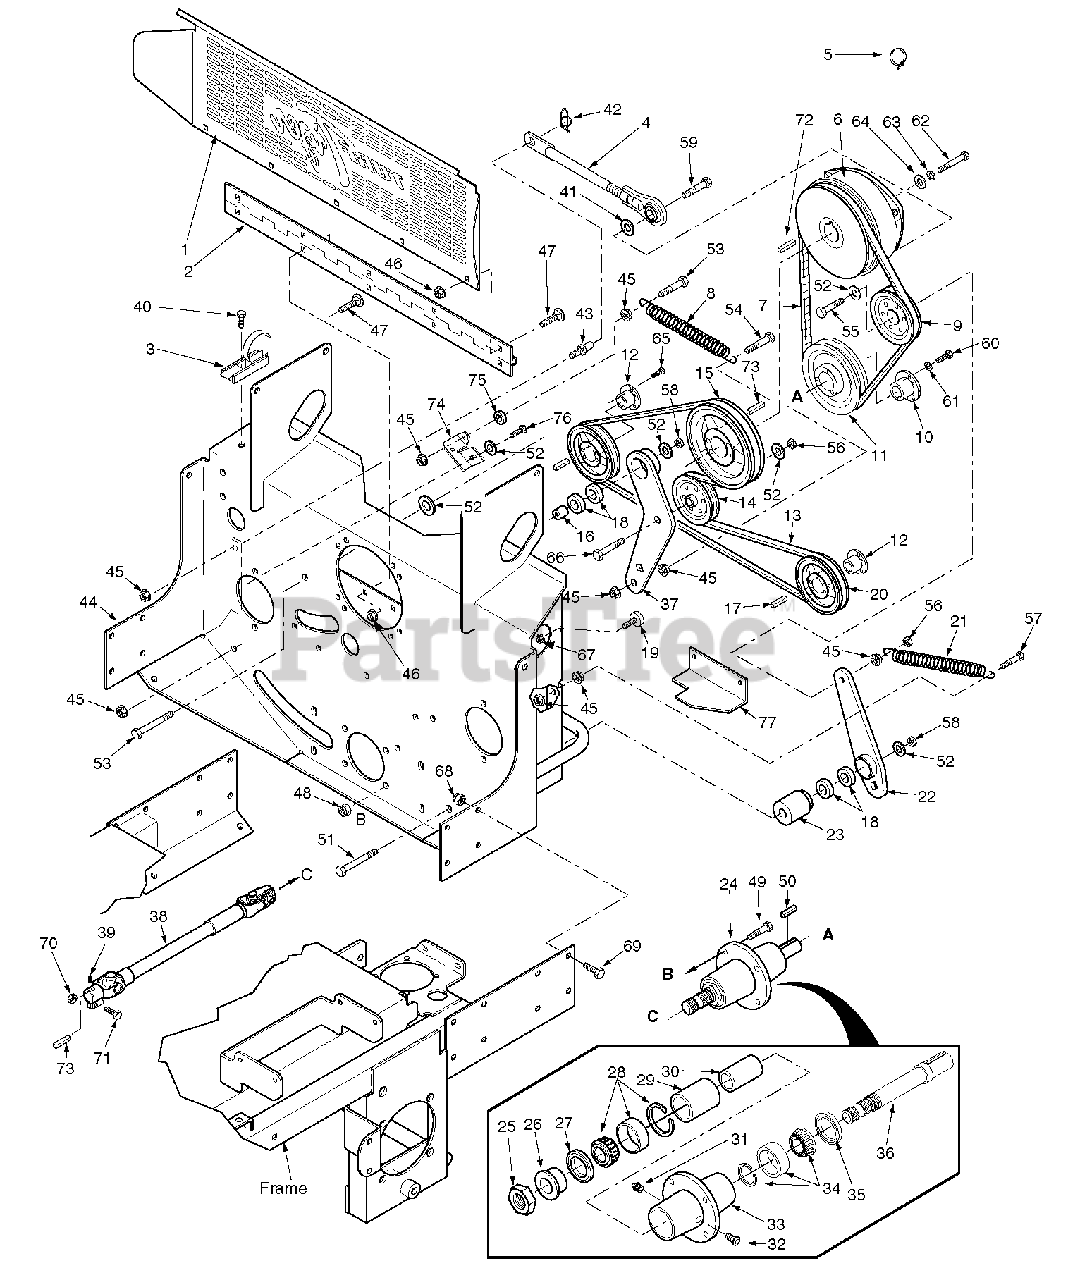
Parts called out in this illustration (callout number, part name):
1	Belt Guard, Rear
2	Hinge, Belt Guard
3	Latch, Hood
4	Rod Assembly, Clutch Anti-Rotation
5	Clamp, Cable
6	Clutch, Ogura GT-3.5
6	Clutch, Ogura GT-5 (35BVAC)
7	Belt, Deck Drive
8	Spring, Transmission Idler
9	Pulley, Idler 5" Dia.
10	Tapered Hub, 1" Bore
11	Pulley, 6.70" Tapered Bore
12	Tapered Hub, 17mm Bore
13	Belt, Pump Drive STT
13	Belt, Pump Drive (26DFI, 26CH-EFI, 35BVAC)
14	Pulley, Idler 4" Dia.
15	Pulley, 4.55" Dia.-1.125" Bore (25KA, 26CH-EFI)
15	Pulley, 5.15" Dia.-1.125" Bore (26DFI, 35BVAC)
16	Spacer, Idler Bearing
17	Key, 5.0 x 5.0 x 25mm
18	Ball Bearing
19	Bumper, Rubber
20	Pulley, 6.35" O.D.
21	Spring, PTO
22	Idler Arm Weldment, PTO Drive
23	Pivot, Idler PTO
24	Spindle Assembly, Deck Drive
25	Nut, 1.06"-18 Thread
26	Spindle Bushing, Bottom
27	Seal, 2.0" OD x 1.625" Bore
28	Roller Bearing Tapered
29	Spacer, Outside
30	Spacer, Inside
31	Grease Fitting, 1/4-28
32	Relief Fitting
33	Spindle Housing
34	Roller Bearing Tapered
35	Seal, 2.0" OD x 1.5" Bore
36	Shaft, Deck Drive
37	Idler Arm Weldment, Pump Drive
38	Driveshaft (Air-Cooled Engine)
38	Driveshaft (Liquid-Cooled Engine & 35BVAC)
39	Set Screw, 3/8-16 x 3/4" Torx Socket
40	Screw, #10-32 x .56"
41	Flatwasher, 3/8 (.391 x .938 x .105")
42	Pin, Rue Cotter 3/8" Dia.
43	Stud, Anti Rotation
44	Pump Mounting Plate Weldment (Liquid-Cooled Kawasaki)
44	Pump Mounting Plate Weldment (Air-Cooled 26EFI Kohler)
44	Pump Mounting Plate Weldment (Air-Cooled Briggs & Stratton)
45	Nut, Serrated Flange 3/8-16
46	Nut, Serrated Flange 1/4-20
47	Bolt, Carriage 1/4-20 x 1/2"
48	Nut, Elastic Stop 5/16-18
49	Bolt, Hex Head 5/16-18 x 1-3/4"
50	Key, 1/4 x 1/4 x 1-1/2"
51	Bolt, Hex Head 3/8-16 x 4-1/2" Grd 8 Black
52	Washer, 3/8" Hardened
53	Bolt, Hex Head 3/8-16 x 1-3/4" Grd 8 Black
54	Bolt, Hex Head 3/8-16 x 1-1/2" Grd 8 Black
55	Bolt, Hex Head 3/8-16 x 2-1/2" Grd.8
56	Nut, Center Lock 3/8-16
57	Bolt, Hex Head 3/8-16 x 1-1/2" Grd 8 Black
58	Nut, Elastic Stop 3/8-16
59	Bolt, Hex Head 3/8-16 x 2"
60	Bolt, Hex Head 1/4-20 x 1-3/8"
61	Lockwasher, 1/4" Spring
62	Bolt, Hex Head 7/16-20 x 2-1/2" UNF
63	Lockwasher, 7/16" Spring
64	Flatwasher, 7/16 (.469 x 1.75 x .25")
65	Bolt, Hex Head 1/4-20 x 1"
66	Bolt, Hex Head 3/8-16 x 1-3/4"
67	Nut, Serrated Flange 5/16-18
68	Nut, Elastic Stop 3/8-16
69	Bolt, Hex Head 3/8-16 x 1"
70	Nut, Center Lock 3/8-16
71	Bolt, Hex Head 3/8-16 x 1-3/4"
72	Key, 1/4 x 1/4 x 2-1/4"
73	Key, 1/4 x 1/4 x 1"
74	Bracket
75	Spacer
76	Bolt, Hex Head 3/8-16 x 1"
77	Bracket, Idler Stop
